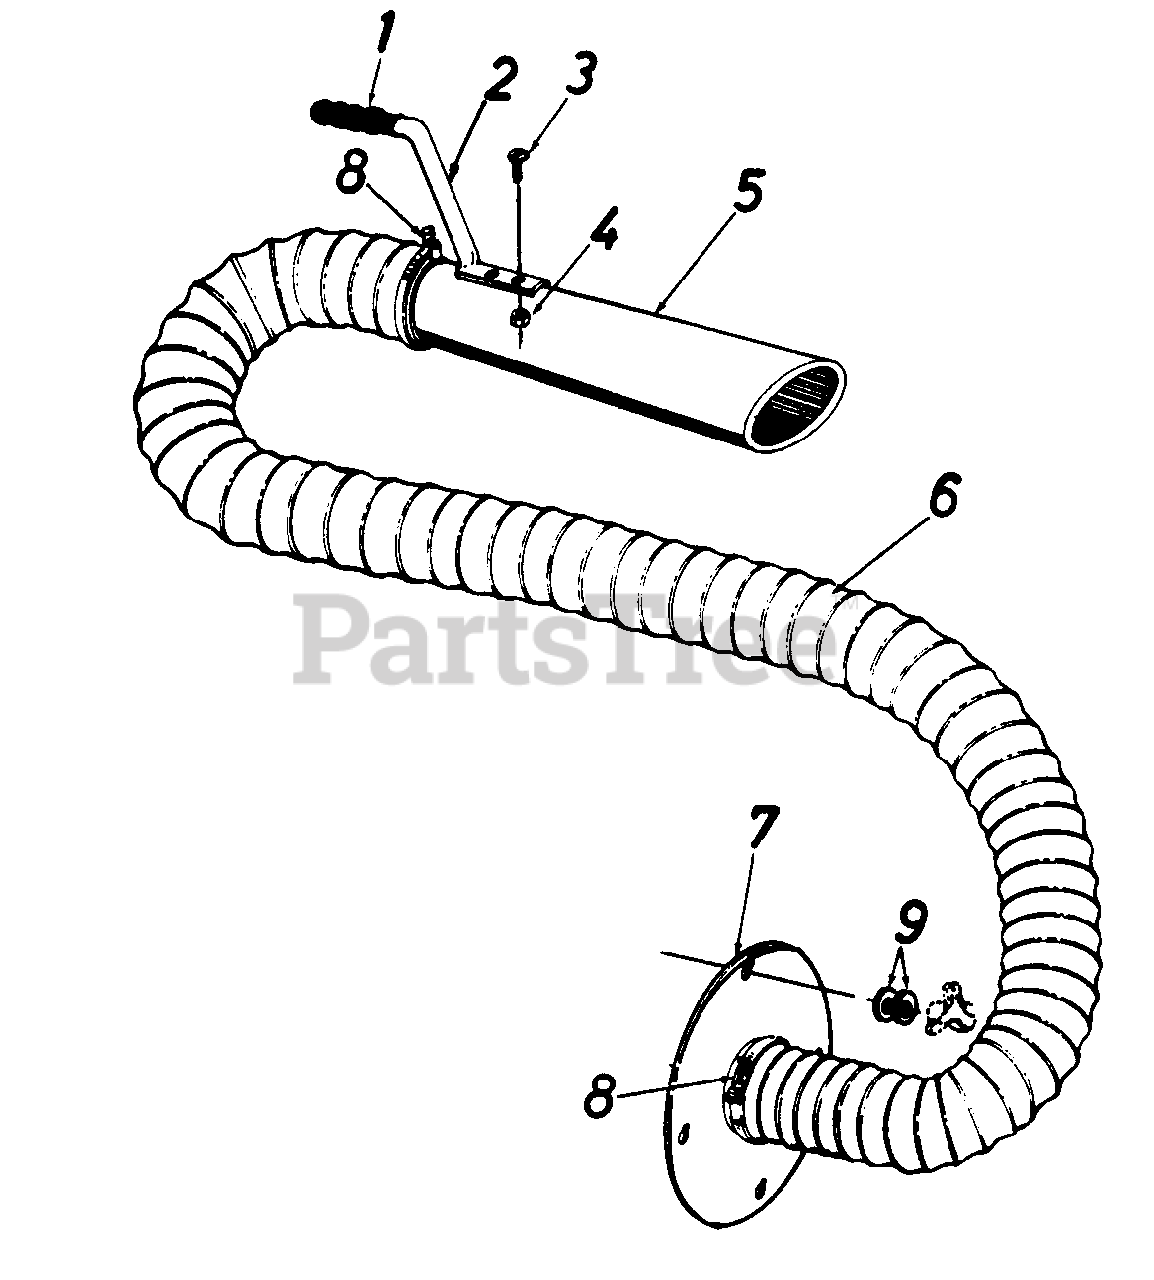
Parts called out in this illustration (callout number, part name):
1	Handle Grip
4	Hex Nut 10-24 Thd.
5	Hose Nozzle
6	Flexible Hose 4" Dia. x 10' Lg.
9	Flat Washer .34 I.D. x 1.12 O.D.
